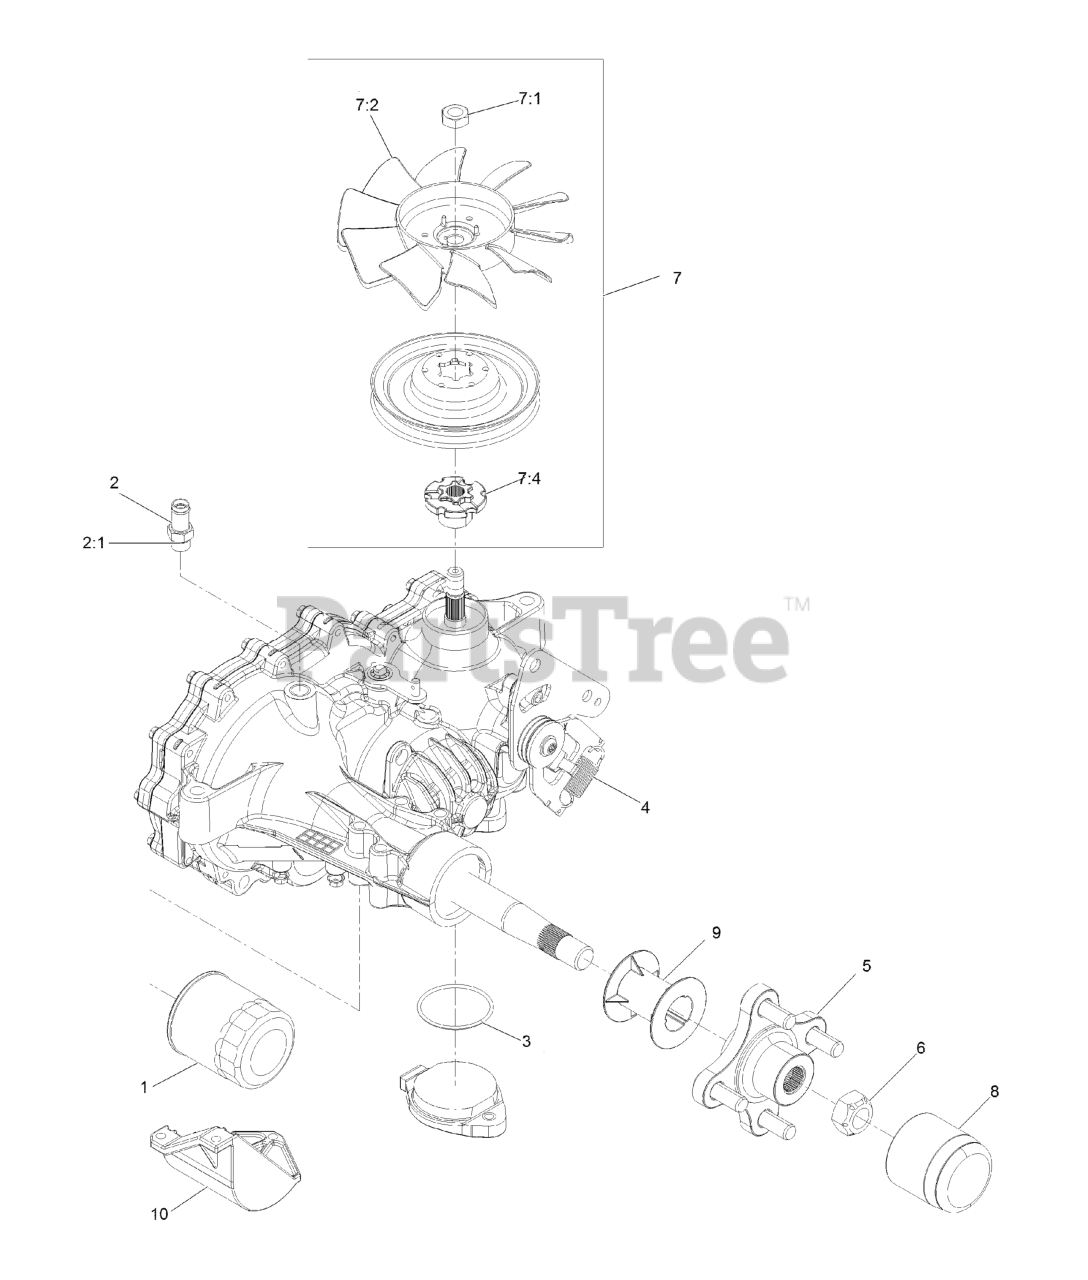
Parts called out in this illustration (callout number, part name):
1	ELEMENT-OIL FILTER, HYD
2	ADAPTER-STRAIGHT
2:1	O-RING
3	O RING-SEAL
4	SPRING-EXTENSION
5	HUB-OFFSET
6	NUT-HUB
7	FAN AND PULLEY KIT
7:4	HUB-PULLEY
8	CAP-AXLE, LONG
9	TUBE-AXLE
10	GUARD-FILTER, RH
99	BRAKE SHAFT SEAL KIT
